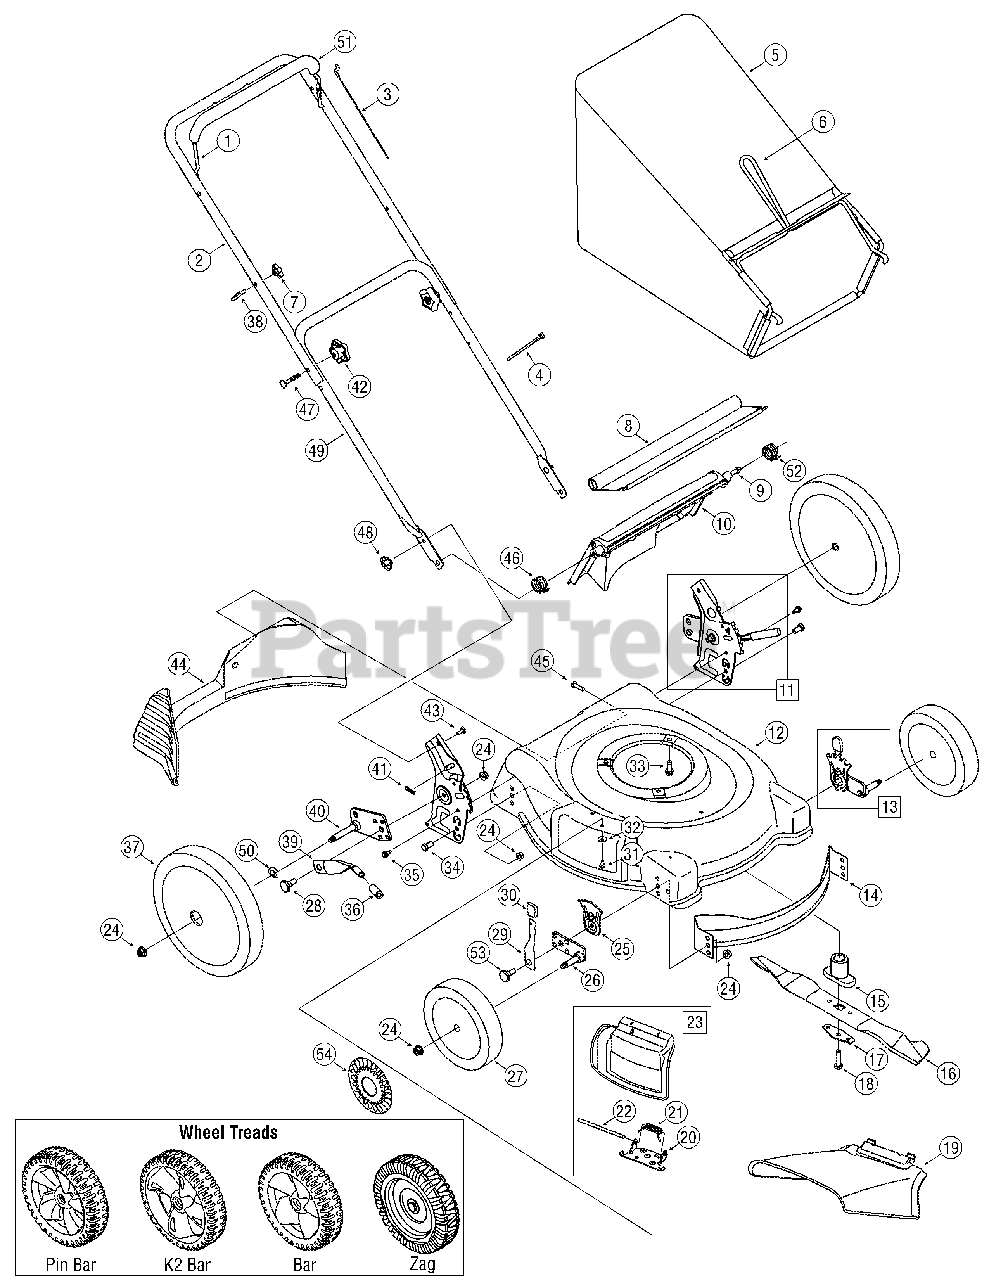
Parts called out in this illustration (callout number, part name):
3	Control Cable, 40"
3	Control Cable, 40", Snap-On
3	Control Cable, 53"
4	Cable Tie
5	Grass Bag Assembly
5	Grass Bag Assembly - Gray
5	Grass Bag Assembly - Yardman
7	Handle Knob
8	Trailshield
9	Pivot Rod
10	Rear Discharge Door
11	Rear Handle Bracket Assy. - LH
11	Rear Handle Bracket Assy. - RH
13	Front Hgt. Adj. Assy., 8" Whl. - RH
13	Front Hgt. Adj. Assy., 7" Whl. - LH
13	Front Hgt. Adj. Assy., 7" Whl. - RH
14	Front Baffle
15	Blade Adapter w/Star
15	Blade Adapter - 25mm
16	21-inch Mulching Blade
17	Bell Blade Support
18	Hex Screw, 3/8-24 x 2.5
19	Side Discharge Chute
20	Deflector Chute Adaptor
21	Torsion Spring
22	Hinge Pin
23	Hinged Mulch Plug Assembly
24	Flange Lock Nut 3/8-16
25	Height Adjustment Plate
26	Pivot Arm Assy LH use position (7" wheel)
26	Pivot Arm Assy RH use position (7" wheel)
26	Pivot Arm Assy RH use position (8" wheel)
26	Pivot Arm Assy LH use position (8" wheel)
27	Front Wheel, 8 x 1.8, K2 Bar
27	Front Wheel, 7 x 1.8, Bar
27	Front Wheel, 8 x 1.8, Bar
27	Front Wheel, 8 x 2.125, Zag
27	Front Wheel, 7 x 1.8, Pin Bar
28	Shoulder Screw, .5D x .434
29	Front Spring Lever
30	Height Adjust Knob
31	TT Screw, 1/4-20 x .500
32	Bell Washer
33	TT Screw, 3/8-16 x 1.0
34	Hex Screw, 3/8-16 x .75
35	TT Screw, 1/4-20 x .625
36	Foam Grip
37	Rear Wheel, 12 x 1.8, K2 Bar
37	Rear Wheel, 12 x 1.8, Bar
37	Rear Wheel, 12 x 2.125, Zag
37	Rear Wheel, 12 x 1.8, Pin Bar
38	Eye Bolt
39	Rear Hi-Wheel Spring Lever
40	Rear Pivot Arm Assy - RH
40	Rear Pivot Arm Assy - LH
41	Hairpin Clip
42	Star Knob
43	Carriage Bolt ,1/4-20 x .75
44	Rear Baffle
45	Screw HL, 1/4-15 x 1.00
46	Torsion Spring - RH
47	Carriage Bolt, 5/16-18 x 2
48	Wing Nut
50	Spring Washer
51	Deluxe Bail Cover - Red
51	Deluxe Bail Cover - Gray
52	Torsion Spring - LH
53	Shoulder Screw, .500 Dia. X .385
54	Hub Cap
